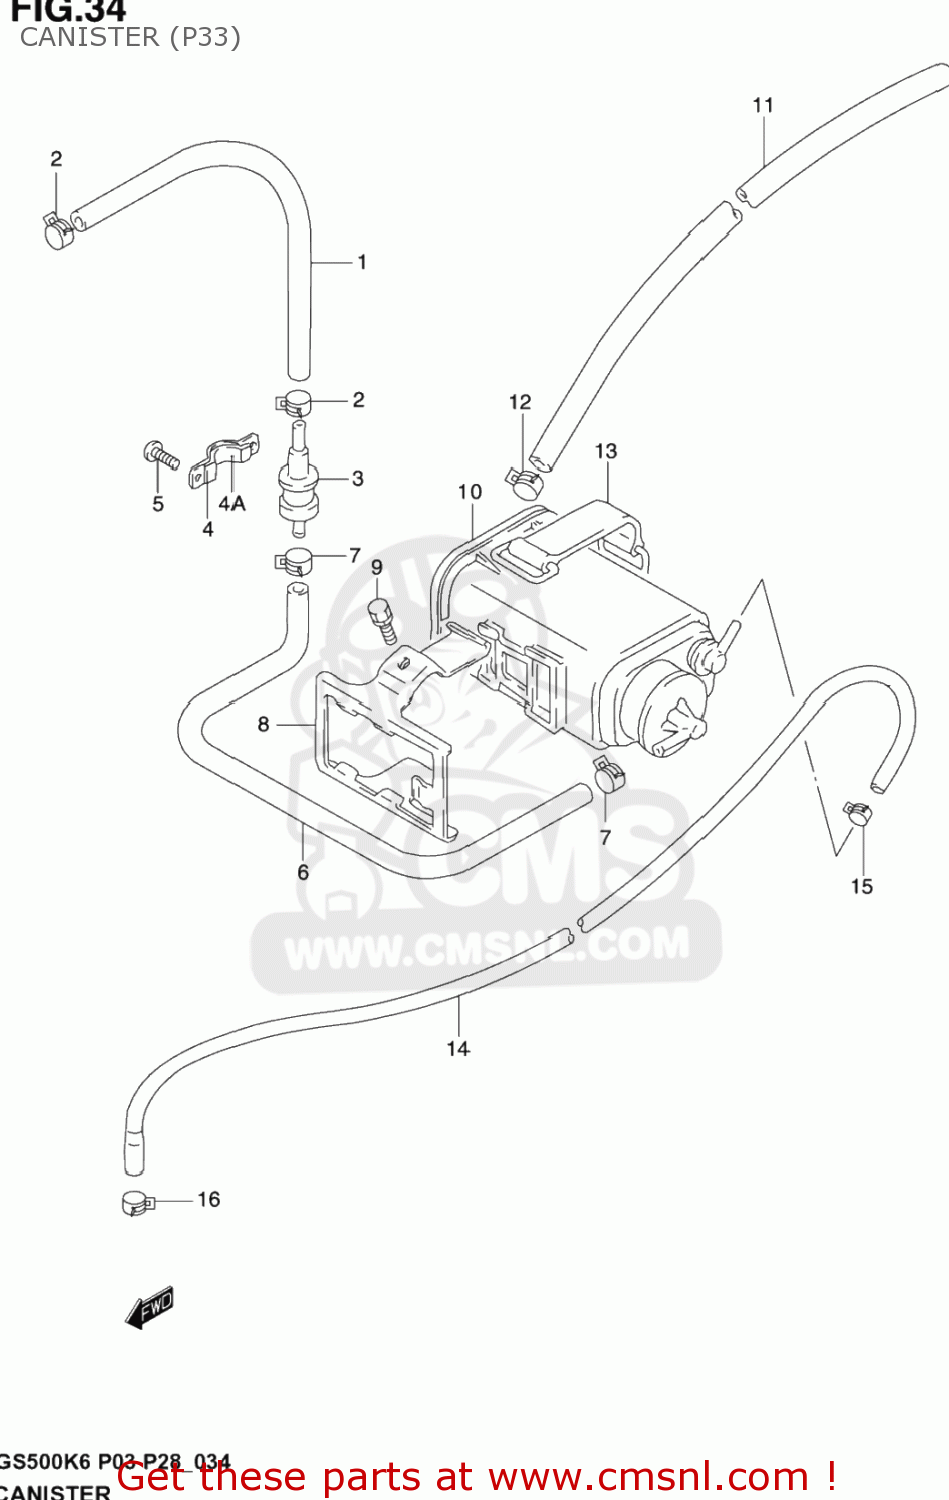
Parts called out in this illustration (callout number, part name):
1	HOSE(5.4X11.4X600)
2	CLIP
3	VALVE,FUEL TANK BREATHER
4	PLATE,FUEL TANK BREATHER NO.2
4A	CUSHION
5	SCREW
6	HOSE(5.4X11.4X350)
7	CLIP
8	PLATE,CSTR FITING
9	BOLT
10	CANISTER ASSY,CHARCOAL
11	HOSE(7X12X600)
12	CLIP
13	BAND
14	HOSE(3.5X7.5X600)
15	CLIP
16	CLIP
